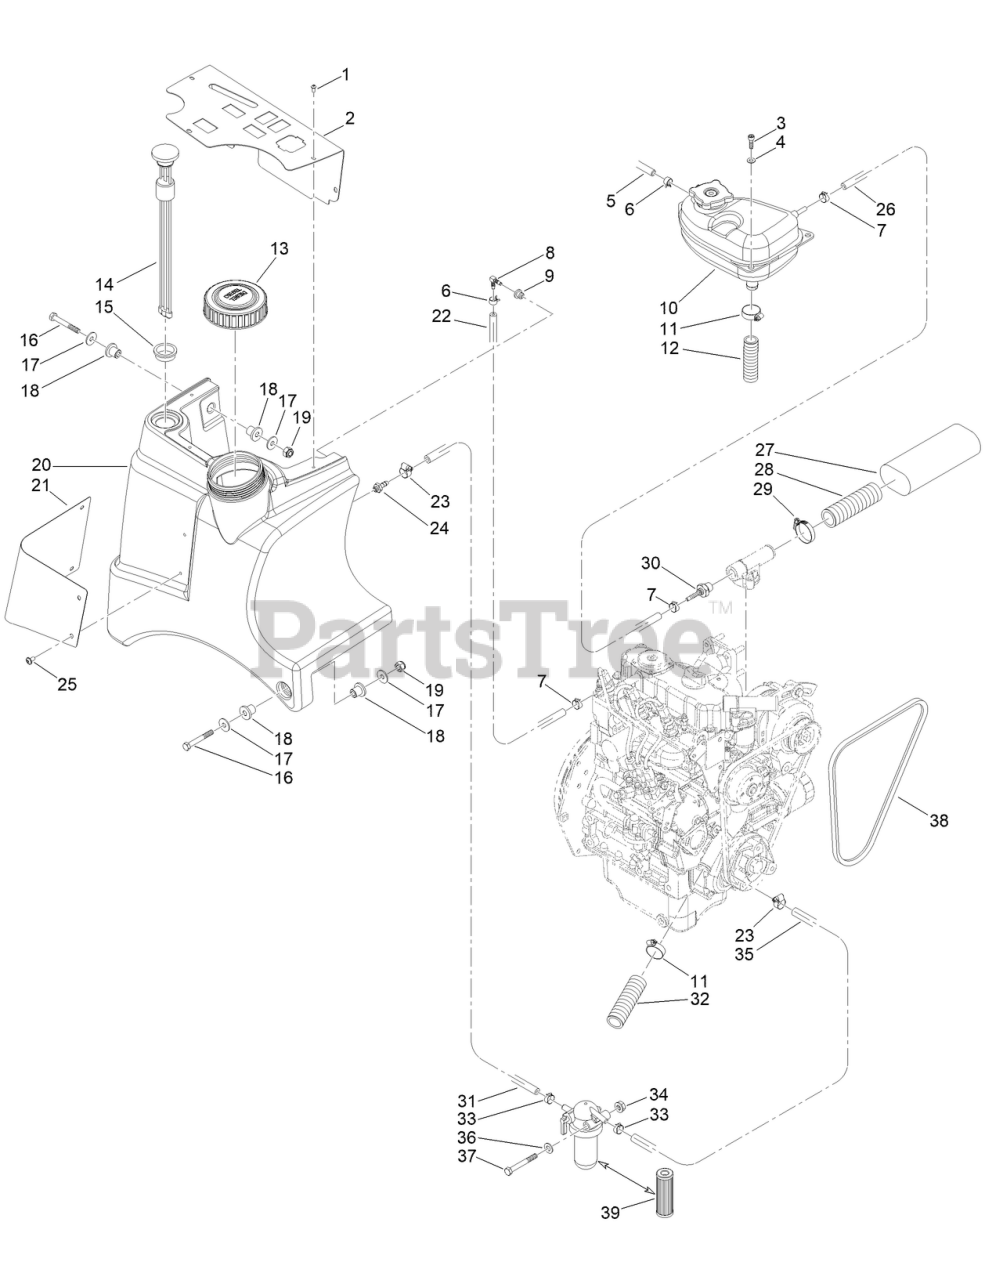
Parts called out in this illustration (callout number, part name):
1	SCREW-H-SCKT B HEAD CAP
2	DASHBOARD, LH
4	WASHER
8	FITTING, 90 DEG
9	GASKET, FITTING WS5
10	WATER EXPANSION TANK
12	HOSE, RADIATOR
13	CAP-TANK, DIESEL
14	FUEL GAUGE
15	GASKET, FUEL GAUGE
17	WASHER
18	BUSHING
20	FUEL TANK
21	COVER, FUEL TANK
23	CLIP-WORM
24	FITTING,
27	HOSE GUARD
28	HOSE, RADIATOR 25X1240
30	FITTING-TAPER
31	HOSE-RUBBER
32	HOSE, RADIATOR
36	WASHER
38	BELT, ENGINE
39	FILTER, GASOLINE
